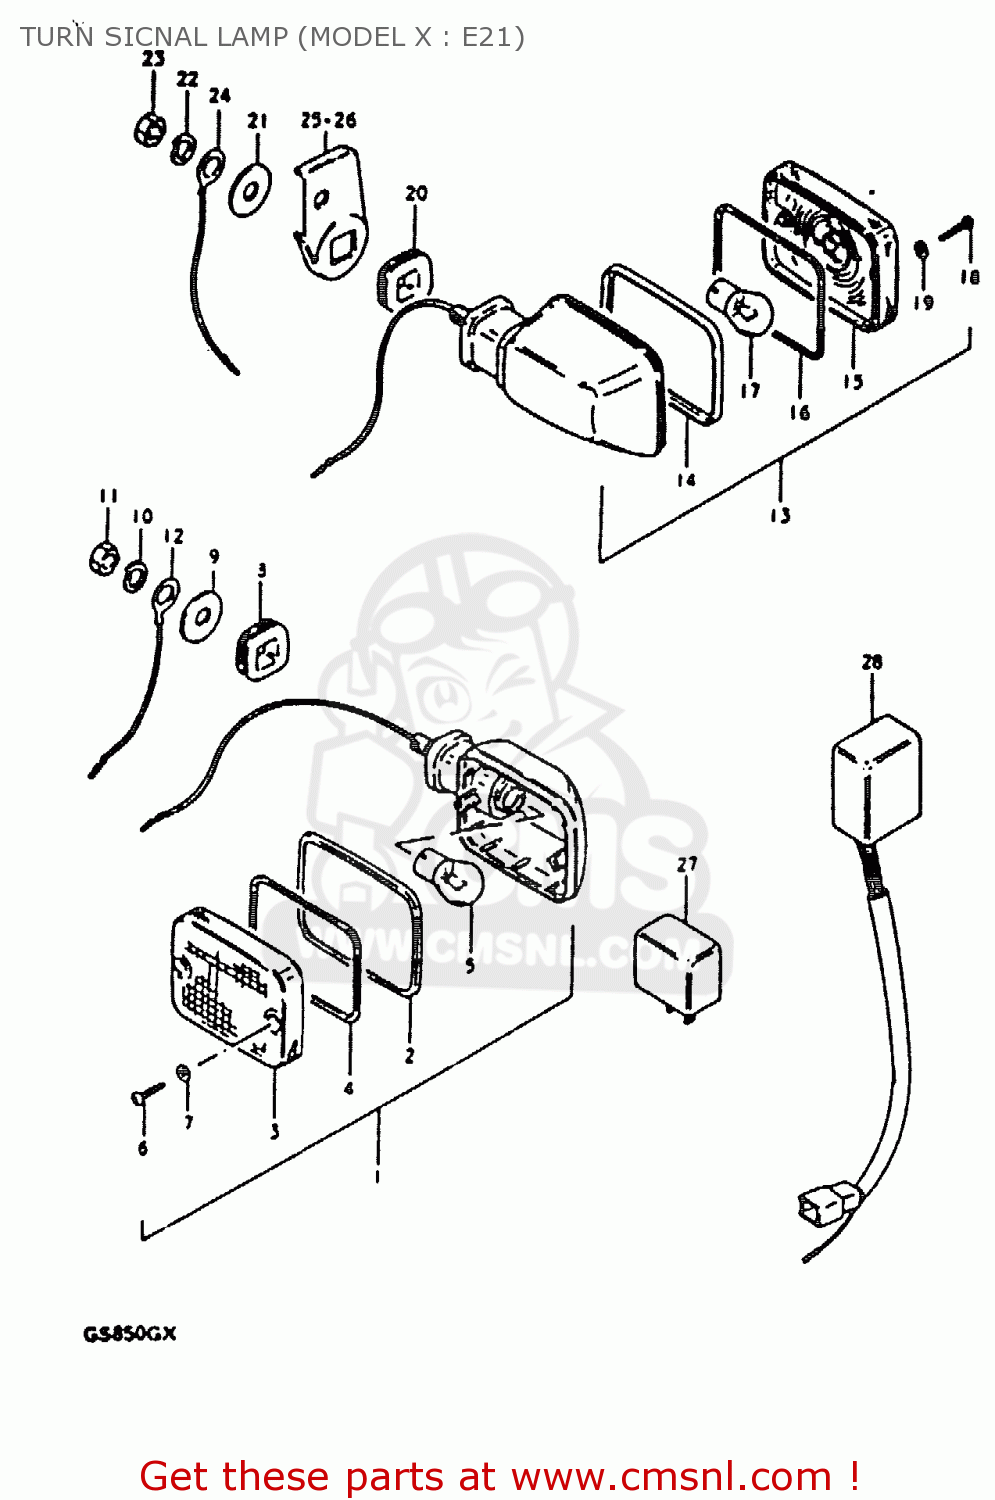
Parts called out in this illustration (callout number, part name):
1	LAMP, FRONT TURN SIGNAL
2	RIM
3	LENS
4	GASKET (NAS)
5	BULB 12V 21W
6	SCREW
7	GASKET (NAS)
8	CUSHION
9	WASHER (10.5X30X2.3)
10	LOCK WASHER
11	NUT
12	LEAD WIRE,EARTH
13	LAMP, REAR TURN SIGNAL
14	RIM
15	LENS
16	GASKET (NAS)
17	BULB 12V 21W
18	SCREW
19	GASKET (NAS)
20	CUSHION
21	WASHER (10.5X30X2.3)
22	LOCK WASHER
23	NUT
24	LEAD WIRE,EARTH
25	BRACKET,RR TURNSIGNAL LAMP,R
26	BRACKET,RR TURNSIGNAL LAMP,L
27	RELAY ASSY,TURNSIGNAL
28	UNIT,TURN SIGNAL CONTROL
